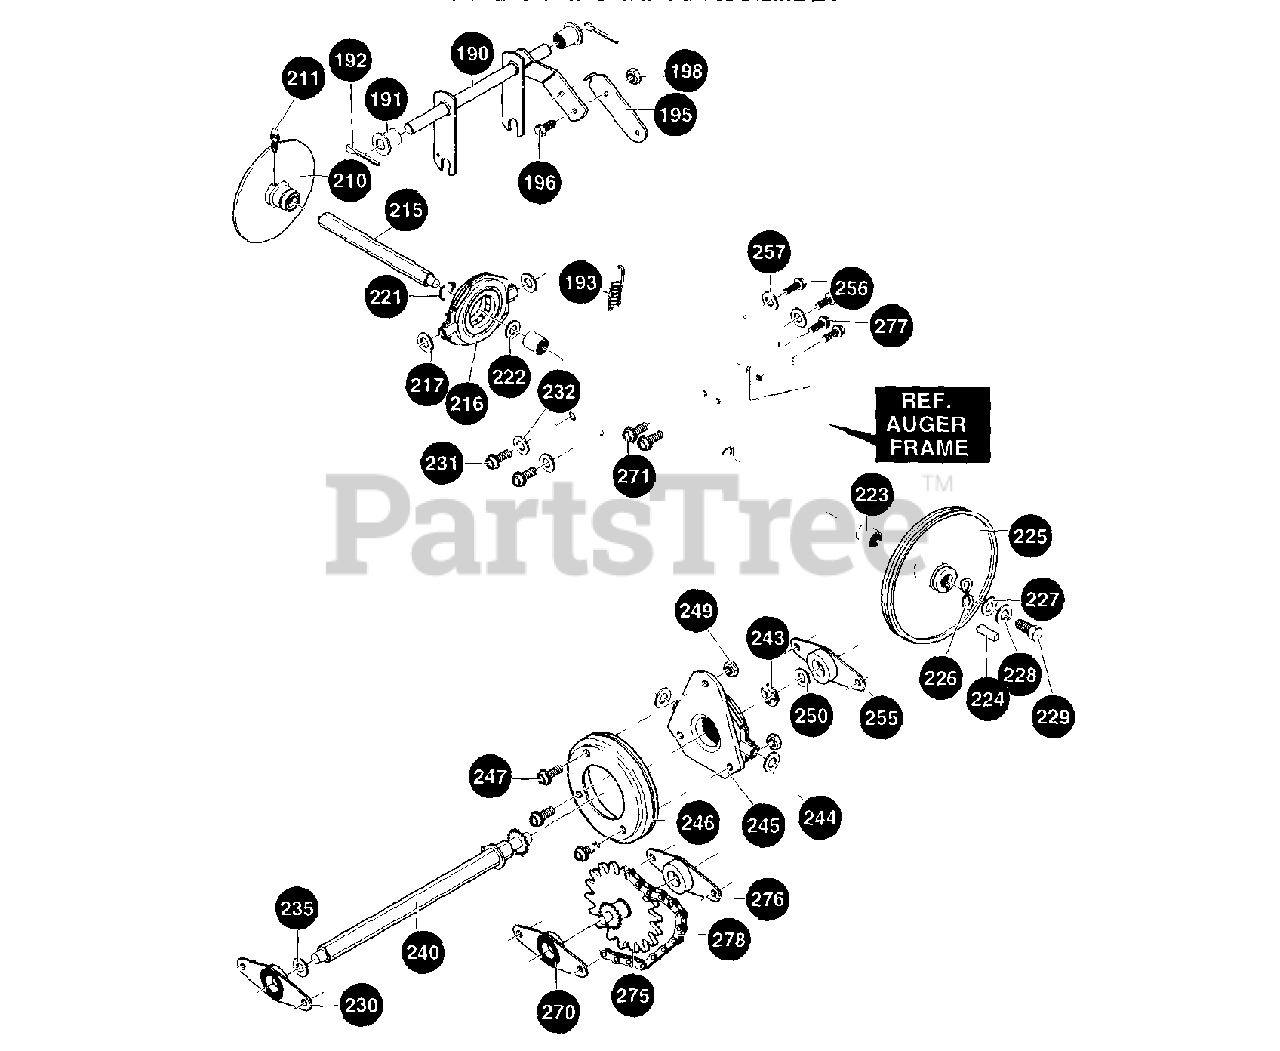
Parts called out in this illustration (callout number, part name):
190	LEVER, ASSY TRACTION
191	BEARING, FLANGE
192	PIN, COTTER
193	SPRING, RETURN
195	LEVER, SPRING
196	SCREW, 1/4-20X 63
198	NUT, 1/4-20
210	DISC, ASSY
211	ZERK, GREASE
215	SHAFT, HEX TRACTION
216	BEARING, TRUNION
217	FLATWASHER, .53 X 1.00 X .063
221	RING, RETEX
222	FLATWASHER, .680 X 1.12 X .060
223	BEARING, BALL
224	KEY, SQUARE
225	PULLEY, V3L 6.50 X .56
226	WASHER, WAVE
227	FLATWASHER, .281 X 1.00 X .063
228	WASHER, .263 X .49 X .07
229	SCREW, 1/4-20 X 75
230	BEARING & RETAINER
231	SCREW, 5/16-18 X 50
232	WASHER, .325 X .60 X .09
235	WASHER, .502 X .75 X .0605
240	HEX, ASSY 440-8T
243	RING, RETEX
244	FLATWASHER, .53 X 1.00 X .063
245	BEARING, TRUNION
246	WHEEL, ASSY FRICTION
247	SCREW, 1/4-20X 63
249	NUT, 1/4-20 HEXKEPS
250	WASHER, .502 X .75 X .0605
255	BEARING 8 RETAINER
256	SCREW, 5/16-18X 50
257	WASHER, 328 X 60 X 09
270	BEARING & RETAINER
271	SCREW, 5/16-18X 50
275	JACK, ASSY #41 36T&7T
276	BEARING & RETAINER
277	SCREW, 5/16-18X 50
278	CHAIN, ROLLER #42 X 40P
